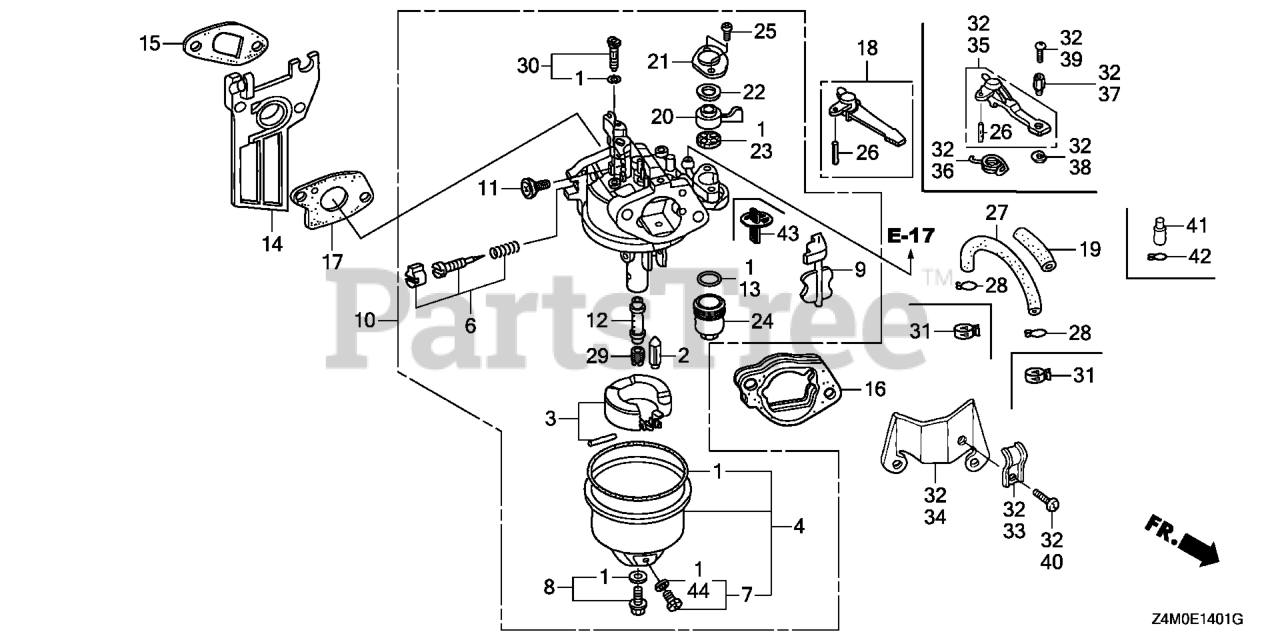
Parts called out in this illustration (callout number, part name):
1	GASKET SET
2	VALVE SET, FLOAT (CARBURETOR NO.) (SEAT NOT INCLUDED)
3	FLOAT SET
4	CHAMBER SET, FLOAT
7	SCREW SET, DRAIN
8	SCREW SET (CARBURETOR NO.)
9	CHOKE SET
10	CARBURETOR ASSY. (BE99M A)
11	SCREW, THROTTLE STOP
12	NOZZLE, MAIN (CARBURETOR NO.)
13	GASKET, FUEL STRAINER CUP
14	INSULATOR, CARBURETOR
15	GASKET, INSULATOR
16	SPACER, CARBURETOR
17	GASKET, CARBURETOR
18	LEVER, CHOKE (STD)
20	LEVER, VALVE
21	PLATE, LEVER SETTING (CARBURETOR NO.)
22	SPRING, PETCOCK LEVER (CARBURETOR NO.)
23	GASKET, VALVE
24	CUP, FUEL STRAINER
25	SCREW, PAN (3X6)
26	PIN, SPRING (2X12)
29	JET, MAIN (#60)
29	JET, MAIN (#62)
29	JET, MAIN (#65)
30	JET SET, PILOT (#40) (ADVENTURE GREEN) (CARBURETOR NO.)
43	FILTER, CUP (CARBURETOR NO.)
44	WASHER, PLAIN (6.2X10.7 DRAIN) (CARBURETOR NO.)
